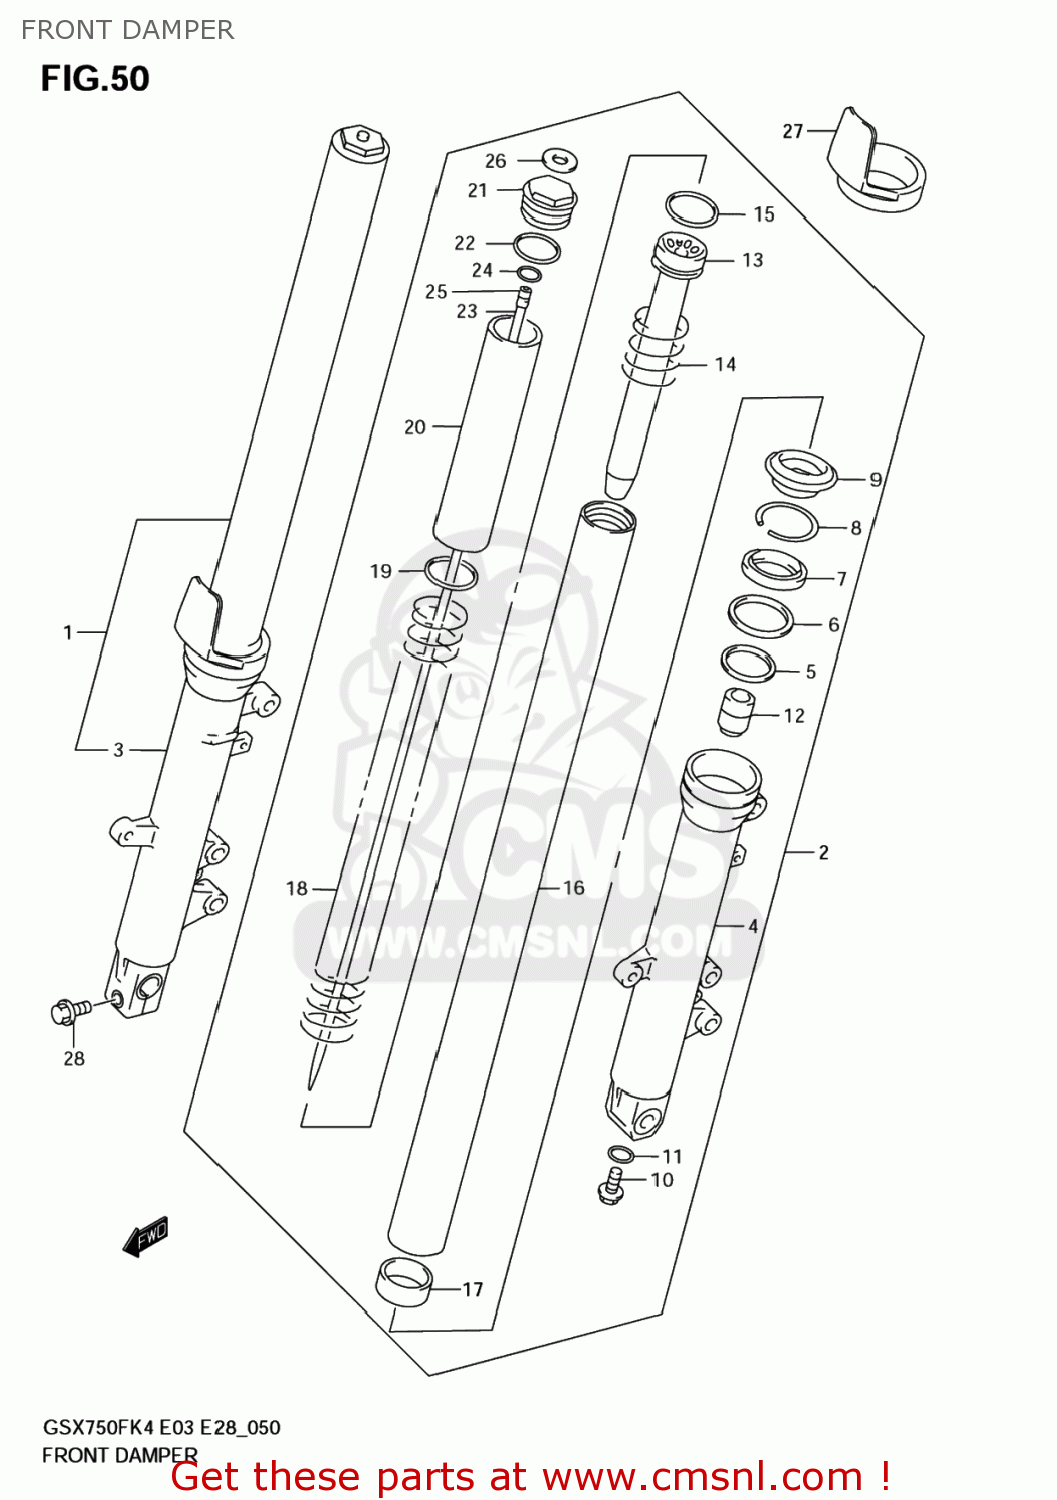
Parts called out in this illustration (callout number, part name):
1	DAMPER ASSY,FR FORK,R
2	DAMPER ASSY,FR FORK,L
3	TUBE,OUTER,R
4	TUBE,OUTER,L
5	BUSH,GUIDE
6	SPACER,SEAL
7	SEAL,OIL
8	CIRCLIP,FORK OIL SEAL
9	SEAL,DUST
10	BOLT(8X27)
11	GASKET (NAS)
12	PIECE,OIL LOCK
13	SEAT,UNDER
14	SPRING,REBOUND
15	RING,PISTON
16	TUBE,INNER
17	BUSH,SLIDE
18	SPRING,FR
19	JOINT,SPRING
20	COLLAR,SPRING
21	BOLT,FORK
22	O RING
23	ROD,DAMPER
24	O RING(D:1.9,ID:3.8)
25	RING,STOPPER(ID:6.1,D:0.6)
26	LABEL,S-H
27	PROTECTOR
28	BOLT
